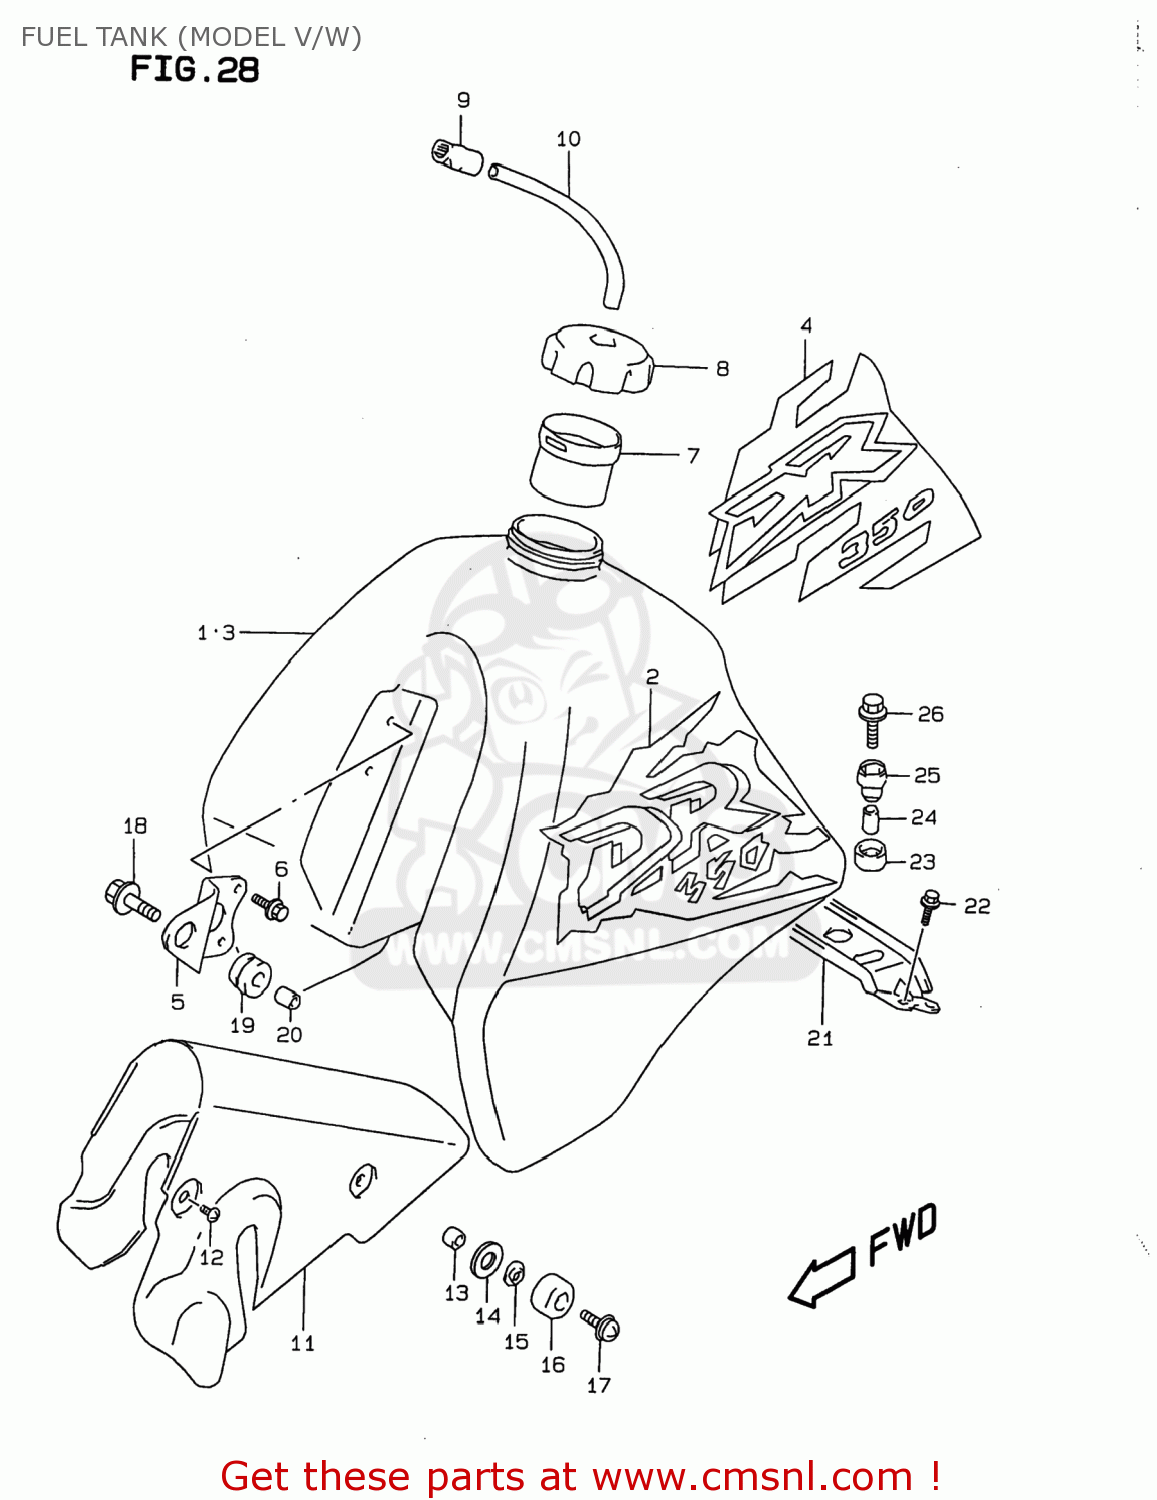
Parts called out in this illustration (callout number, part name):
1	TANK ASSEMBLY,FUEL
2	TAPE SET,FUEL TANK
3	TANK ASSEMBLY,FUEL
4	TAPE SET,FUEL TANK
5	BRACKET,FUEL TANK,FRONT
6	BOLT
7	TUBE,FILLER INLET
8	CAP ASSY,FUEL TANK
9	CLAMP,BREATHER HOSE
10	HOSE(5X8.2X600)
11	HEAT SHIELD,FUEL TANK
12	BOLT
13	SPACER(6.1X14X7.2)
14	WASHER(6.5X26X2.3)
15	WASHER
16	CUSHION
17	SCREW
18	BOLT
19	CUSHION
20	SPACER(8.5X12X12.5)
21	BRACKET,FUEL TANK RR
22	BOLT
23	CUSHION
24	SPACER(6.5X9X18)
25	CUSHION
26	BOLT(6X30)
